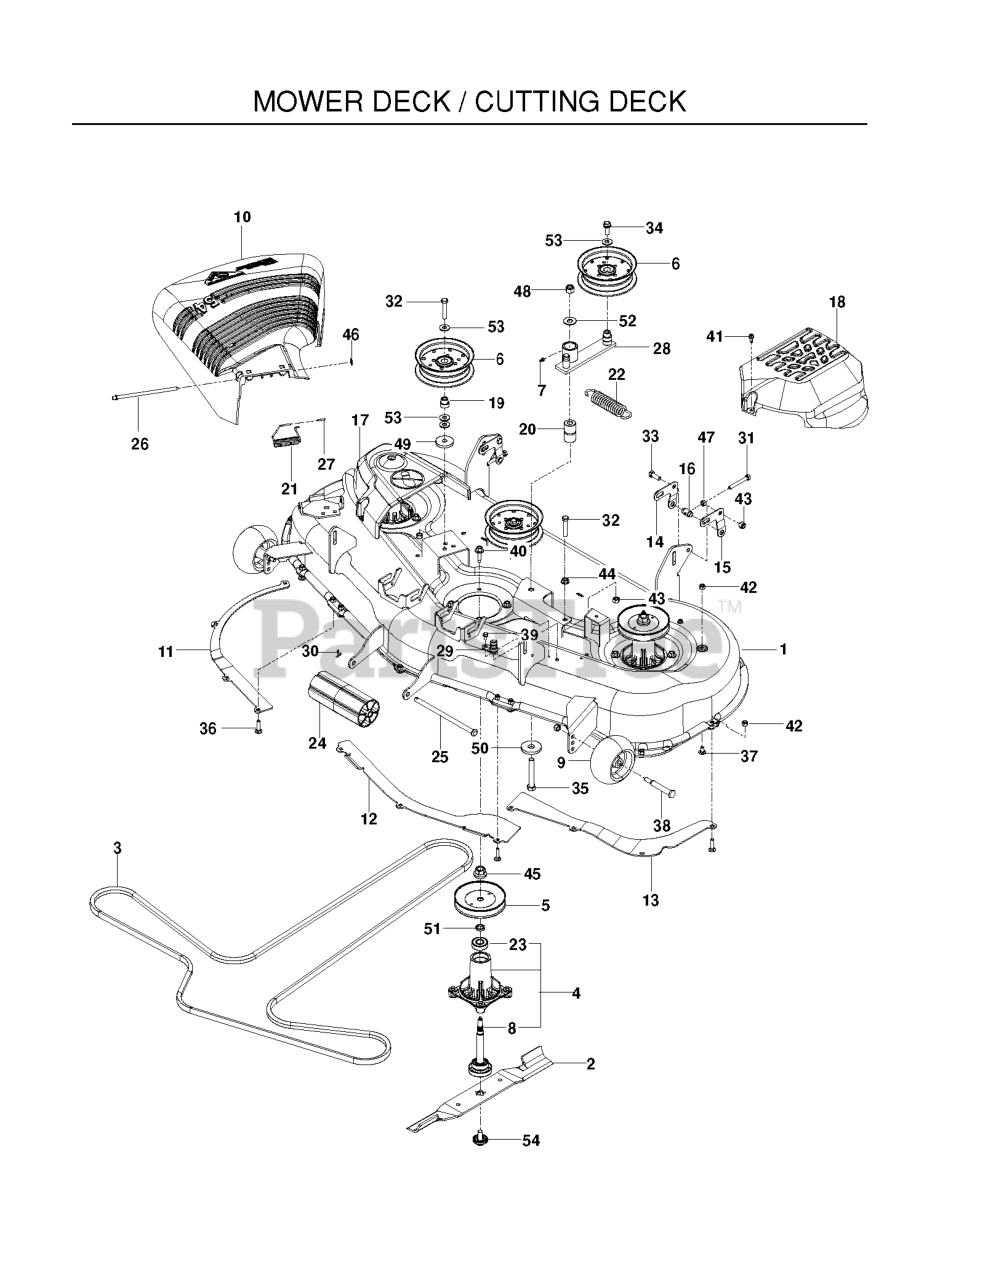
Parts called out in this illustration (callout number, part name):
1	DECK.SVC W/DECALS.54.MZ.ORANGE
2	BLADE.BAGGING.54"
3	BELT.DECK.EL=152.9
4	MANDREL GREASABLE
5	PULLEY
6	PULLEY, IDLER
7	ZERK
8	GREASABLE MANDREL SHAFT
9	GAUGE WHEEL
10	DEFLECTOR, 54"
11	BAFFLE, RIGHT 54"
12	BAFFLE, CENTER, 54"
13	BAFFLE LEFT 54
14	PITCH, ADJUST, RT
15	PITCH, ADJUST, LT
16	TRUNION, PITCH
17	COVER.MANDREL.RH.DECK.54"
18	COVER.MANDREL.LH.DECK.54"
19	IDLER BUSHING
20	PIVOT BUSHING
21	TORSION SPRING
23	BEARING, BALL
24	NOSE ROLLER 48"
25	NOSE ROLLER ROD
26	ROD, HINGE
27	CAP-SLEEVE
29	PORT.WASHOUT
30	RP_COTTER PIN 1/8 X 3/4
32	HCS 3/8C X 2
33	HCS 3/8-16X1.GRD.5.ZD
34	4CS 3/8C X 1 SERRATED HEAD
35	HCS 1/2C X 3 1/4
36	BOLT, CARRIAGE 5/16X1-1/4
37	CARRIAGE BOLT 5/16C X 5/8"
38	SHOULDER BOLT 1/2X2-5/8 ZD SPE
39	BOLT 1/4-20 X 1/2 HWST
40	WASHER HEAD SCREW
41	SCREW- 1/4-20 X 5/8
42	NUT 5/16 NYLOC
43	NUT 3/8-16 NYLOC
44	NUT 3/8C WHIZ
45	LOCKNUT - 9/16
46	PUSH NUT
47	NUT 5/16C HEX
48	NUT 1/2-13 HEX NYLOC ZD
49	SPINDLE WASHER
50	WASHER, SUPPORT
51	WASHER-SPACER
52	WASHER 1/2 FLAT
53	WASHER 3/8 FLAT
54	BOLT.WASHER.ASM.7/16-2
